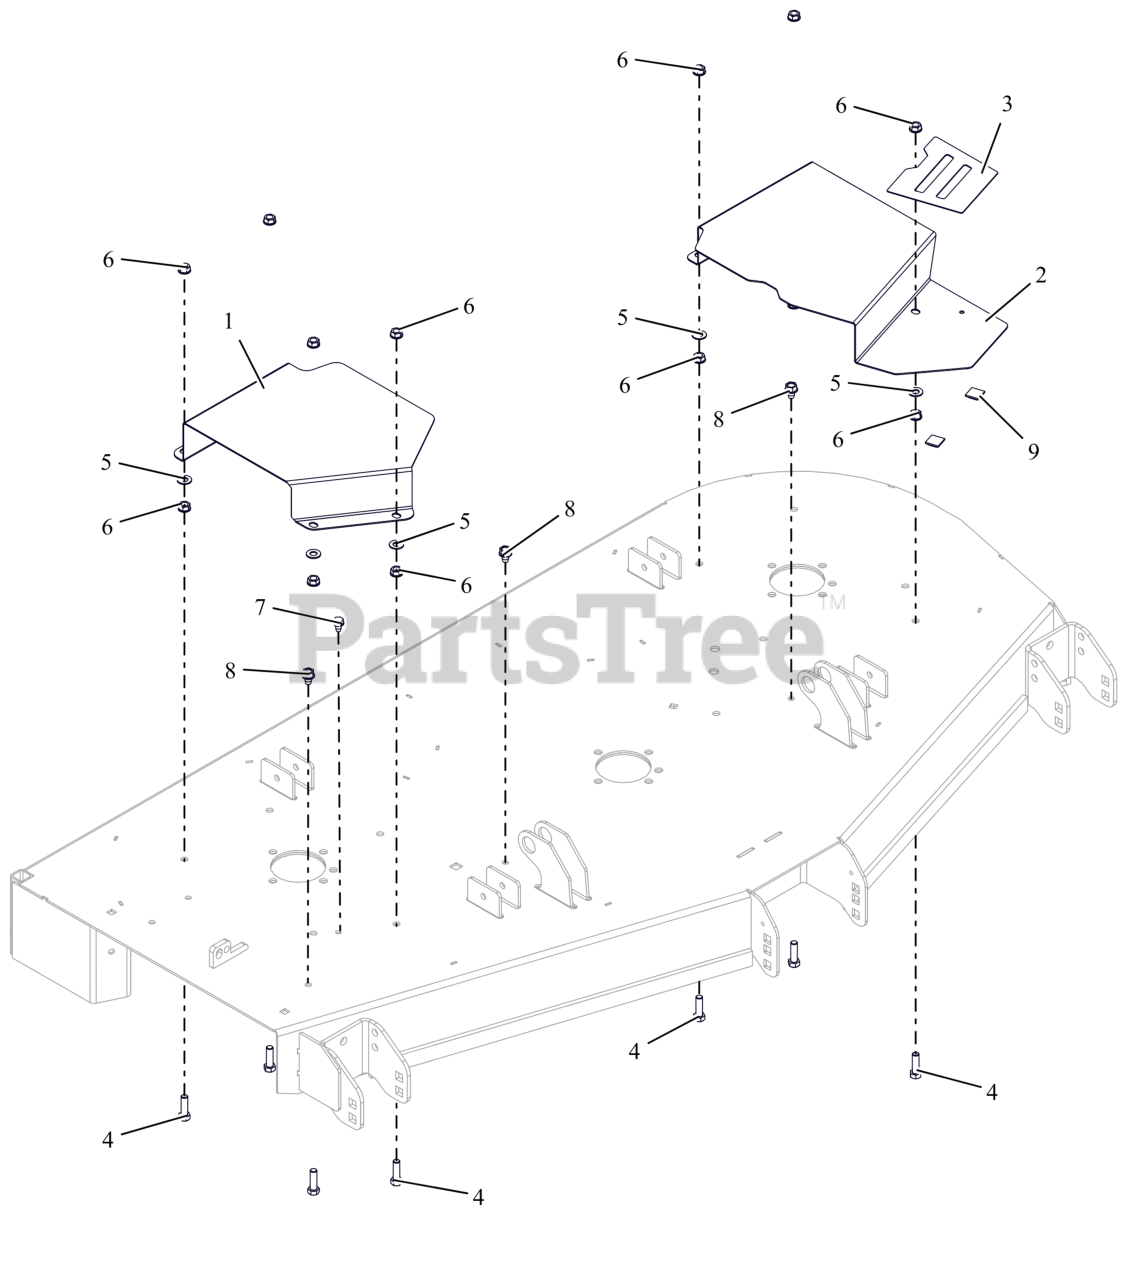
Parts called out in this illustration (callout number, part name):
1	COVER, BELT 52" & 60" RIGHT
2	COVER, BELT 60" LEFT
3	GRIP, TAPE 52-60 BELT COVER
4	BLT, HEX .38-16X1.25 G5 ZCC
5	WSHR,FLT .406X.812X.065 ZCC
6	NUT, SPNLK-FLG .38-16 G5 ZCC
7	SCR,TAP .312-18X.50 HWH TR ZCC
8	SCR,TAP .375-16X.50 HWH TR ZCC
